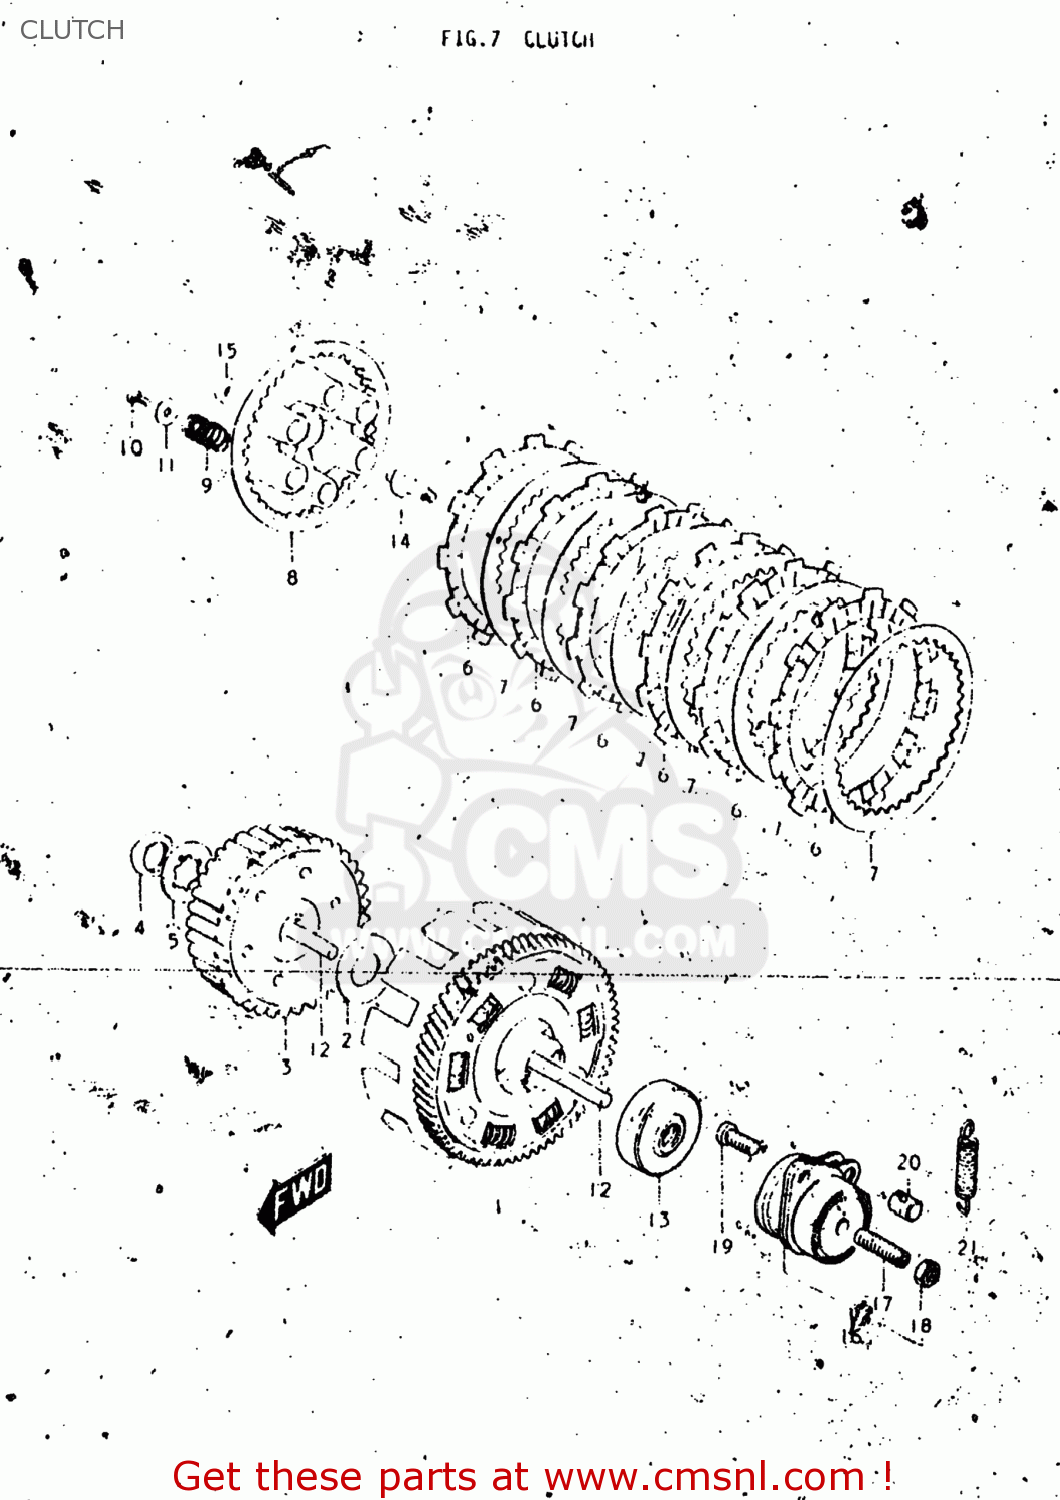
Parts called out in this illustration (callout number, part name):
1	GEAR ASSEMBLY,PRIMARY DRIVE
2	WASHER(20X44X3)
3	HUB,CLUTCH SLEEVE
4	NUT (20MM)
5	WASHER,LOCK
6	PLATE,CLUTCH DRIVE (MCA)
7	PLATE,CLUTCH DRIVEN(T:2.0) (NAS)
8	DISC,CLUTCH PRESSURE
9	SPRING
10	BOLT
11	WASHER
12	ROD,CLUTCH PUSH
13	OIL SEAL
14	ROD,CLUTCH RELEASE
15	SEAL,OIL (10X17X5)
16	SCREW ASSEMBLY,CLUTCH RELEASE
17	SCREW
18	NUT
19	SCREW 6X12
20	PIECE,RELEASE ARM END
21	SPRING
